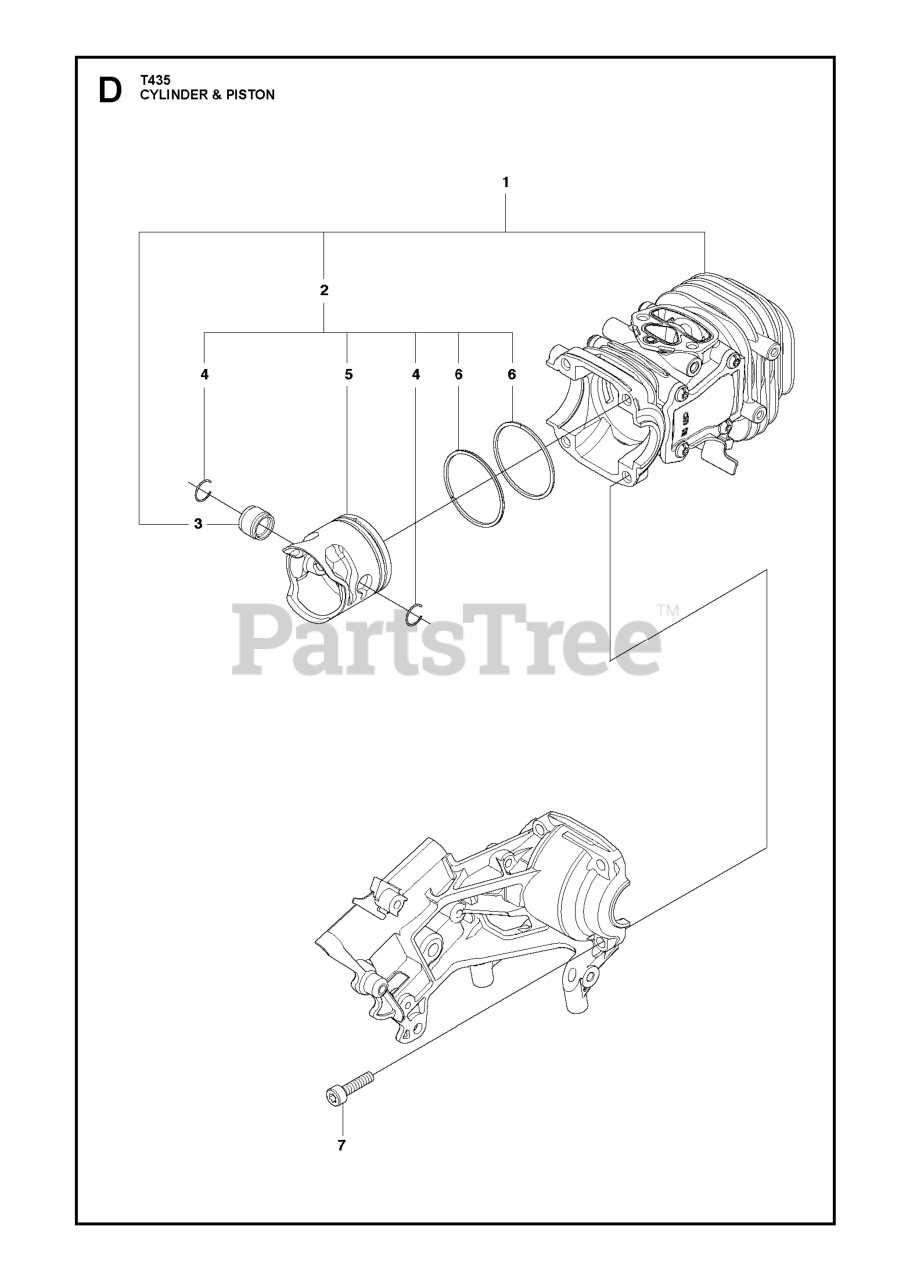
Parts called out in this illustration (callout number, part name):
3	ROLLER BEARING
6	RING, PISTON
7	SCREW
